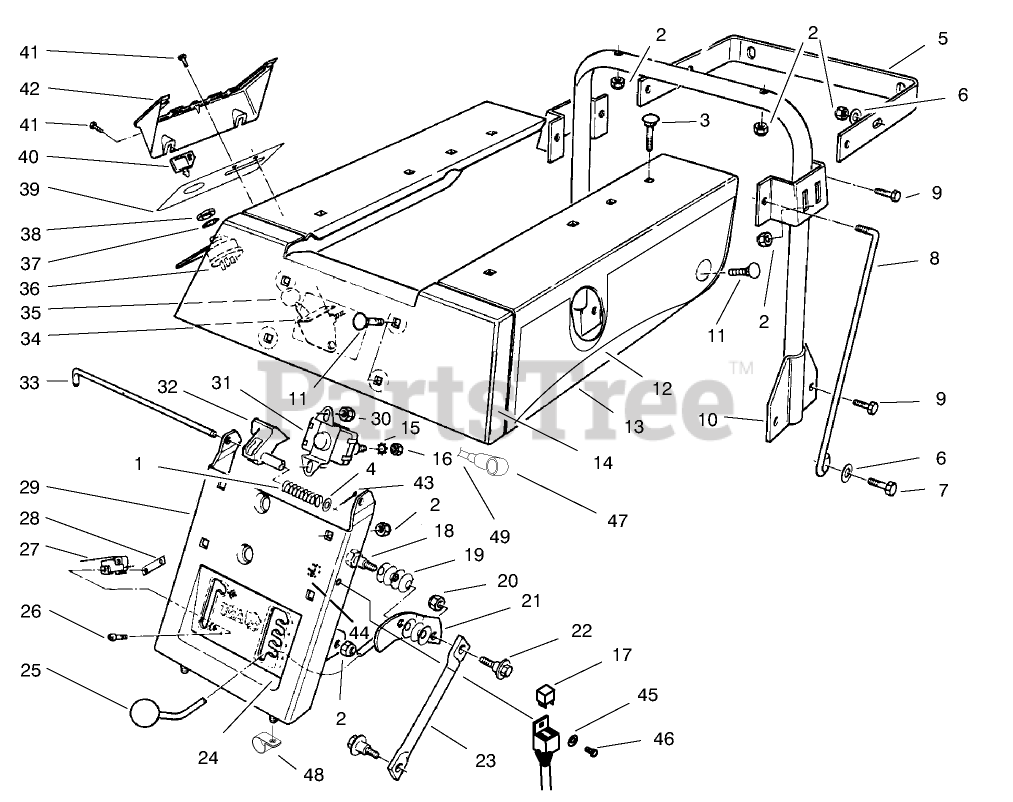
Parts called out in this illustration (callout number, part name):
1	SPRING-COMPRESSION
2	NUT-LOCK, NI
3	SCREW-CARR
4	WASHER-FLAT
5	STANDBAR
6	WASHER-PLAIN
7	SCREW-HH
8	BRACE-SEAT SUPPORT
9	SCREW-HH
10	SEAT SUPT ASM
11	BOLT-CARR
12	DECAL - RH SIDE PANEL
13	SEAT BODY WA
14	DECAL - W.H. INSIGNA
15	WASHER-LOCK
16	NUT-JAM
17	RELAY
18	BOLT-SHOULDER
19	WASHER-BELLEVILLE
20	NUT-LOCK, NI
21	HOC HDLE WA
22	BOLT-SHOULDER
23	LINK-HOC
24	DECAL - HOC/DECK ENGAGE
25	KNOB-CONTROL
26	SCREW-SPH
27	SWITCH-MICRO
28	NUT-SPEED
29	SEAT SUPPORT ASM
30	NUT-LOCK, NI
32	PROP-SEAT
33	ROD-SEAT BASE
34	CONTROL-THROTTLE
35	KNOB-CONTROL
37	WASHER-LOCK
38	NUT-HH
40	KEY-IGNITION
41	SCREW-THD FORM, HWH
43	PIN-COTTER
44	NUT-LOCK, NI
45	WASHER-FLAT
47	BOOT-INSULATOR, TERMINAL
48	CLIP-FUEL LINE
49	ASM - CABLE
